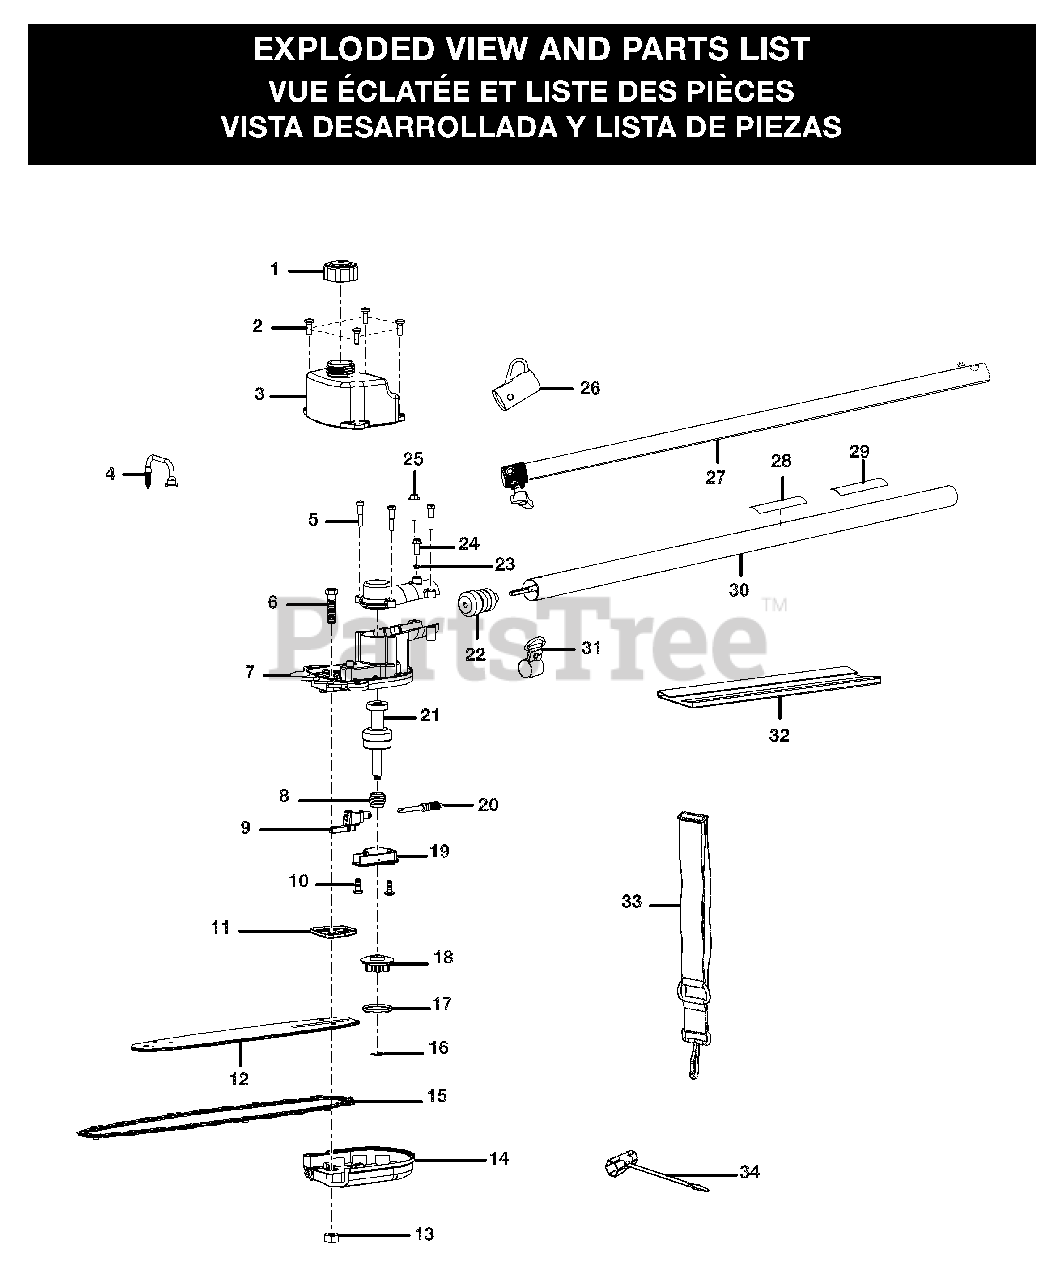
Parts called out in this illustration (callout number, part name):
1	Oil Cap Assembly
2	Screw (M5 x 18 mm)
3	Oil Tank Cover Assembly
4	Oil Pickup Assembly
5	Screw (M5 x 25 mm)
6	Screw (M8 x 35 mm)
7	Gear Case Assembly
8	Worm Gear
9	Oil Pump Seal Assembly
10	Screw (M5 x 13 mm)
11	Bar Pad Plate
12	Guide Bar
13	Hex Nut (M8)
14	Bar Clamp Assembly
15	Chain (10 in.)
16	E-ring (Ø6 mm)
17	Cupped Washer
18	Sprocket
19	Oil Pump Housing w/Cam Pin Assembly
20	Pinion Gear & Plunger Assembly
21	Output Shaft Assembly
22	Pinion and Bearing Assembly
23	Lock Washer (5 mm)
24	Screw (M5 x 15 mm)
25	Screw (M5 x 25 mm)
26	Hanger Cap
27	Intermediate Boom Assembly
28	Logo Label
29	Warning Label
30	Lower Drive Shaft Assembly
31	Strap Hanger
33	Shoulder Strap
34	Wrench
